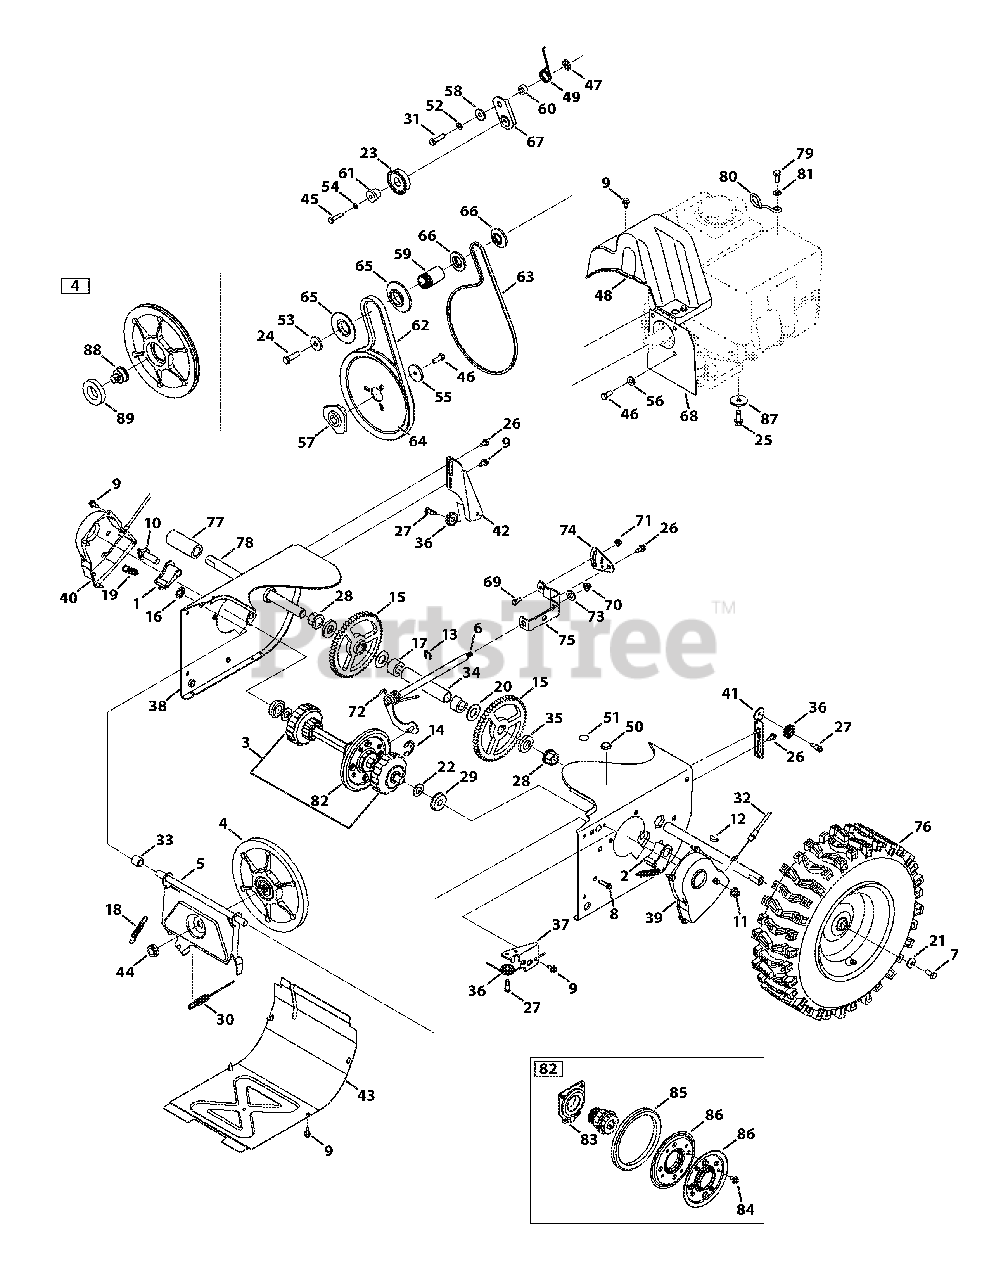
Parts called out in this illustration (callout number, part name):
1	Dogg Assembly, RH
2	Dogg Assembly, LH
3	Drive Shaft Assembly
4	Friction Wheel Disc Assembly
5	Friction Wheel Support
6	Rod Shift Assembly
7	Hex Head Screw, 5/16-24 x .750
8	Screw, 1/4-20 x 1.000
9	Screw, 1/4-20 x .625
10	Actuator Shaft
11	Nut, Flangelock, 3/8-16
12	Hi-Pro Key, 3/16 x 3/4 DIA
14	Retainer Ring
16	Nut, Speed, .500
17	Spacer, .76ID x .75 LG
18	Extension Spring, .380 x 2.500
19	Extension Spring, .500 x 1.71
20	Washer, Flat, .76 x 1.49 x .06
21	Washer, Bell, .340 x .872 x .060
22	Washer, Flat, .58 x 1.125 x .08
23	Pulley Assembly
24	Hex Head Screw, 3/8-24 x 1.25
25	TT Sems Screw, 3/8-16 x 1.000
26	Screw, Shoulder, .368 x .113 x 1/4-20
27	C Screw, Shoulder, .340 x .335 x 1/4-28
28	Hex Flange Bearing, .75 ID
29	Ball Bearing, .5625 x 1.375 x .4375
30	Drive Clutch Cable, 44.955 LG
31	Hex Head Screw, 5/16-24 x 1.25
32	Steering Cable
33	Spacer, .508 ID x .75O OD x .68
34	Axle Support Tube
35	Spacer, Axle
36	Roller Cable
37	Auger Cable Guide Bracket
38	Wheel Drive Frame
39	Shaft Retainer, LH
40	Shaft Retainer, RH
41	Auger Clutch Cable Guide Bracket
42	Drive Clutch Cable Guide Bracket
44	Nut, Flange, 5/8-18
45	TT Screw, 1/4-20 x 1.250
46	Hex Head Screw, 5/16-24 x .875
47	Nut, Push-On, .25 DIA
48	Belt Cover
49	Spring, Torsion, .850 ID x .333 LG
50	Plug, 3/8 ID
51	Plug, 1/2 ID
52	Washer, Lock, 5/16
53	Washer, Flat, .406 x 1.25 x .157
54	Washer, Lock, 1/4
55	Washer, Flat, .34 x 1.50 x .150
56	Shoulder Spacer
57	Pulley Adapter, .75 DIA
58	Spacer, Shoulder, .3175 x .500 x .0975
59	Spacer, .875ID x 1.185OD
60	Spacer, .340 x .750 x .330 LG
61	Spacer, Shoulder, .260 x .785 x .538
62	Belt, .500 x 37.00 LG
63	V Belt, 3/8 x 35.68"
64	Auger Pulley, 8.1 x .5
65	Pulley, Half, 4L-V x 2.600 OD
66	Pulley, Half, 3/8-V x 1.7160 OD
67	Drive Idler Bracket
68	Cover Plate
69	Hex Head Screw, 1/4-20 x .620
70	Nut, Flangelock, 5/16-18
71	Nut, Flangelock, 1/4-20
72	Spring, Torsion, .750ID x .968LG
73	Washer, Flat, .469 x .875 x .105
74	Speed Selector Pivot Bracket
75	Speed Selector Shift Bracket
77	Spacer, 1.25OD x .75ID x 3.00 LG
78	Axle, .75OD x 11.12 LG
79	Hex Head Screw, 1.25 x 20
80	Cable Guide
81	Washer, Flat, .330 x .630 x .0365
82	Friction Wheel Assembly
83	Bearing Assembly, Friction Wheel
84	Screw, 1/4-14 x .625
85	Friction Wheel, 5.5 OD
86	Friction Wheel Plate
87	Washer, Flat, .38 x 1.38 x .125
88	Friction Pin, Disc Bearing
89	Ball Bearing, 30 x 55 x 13
